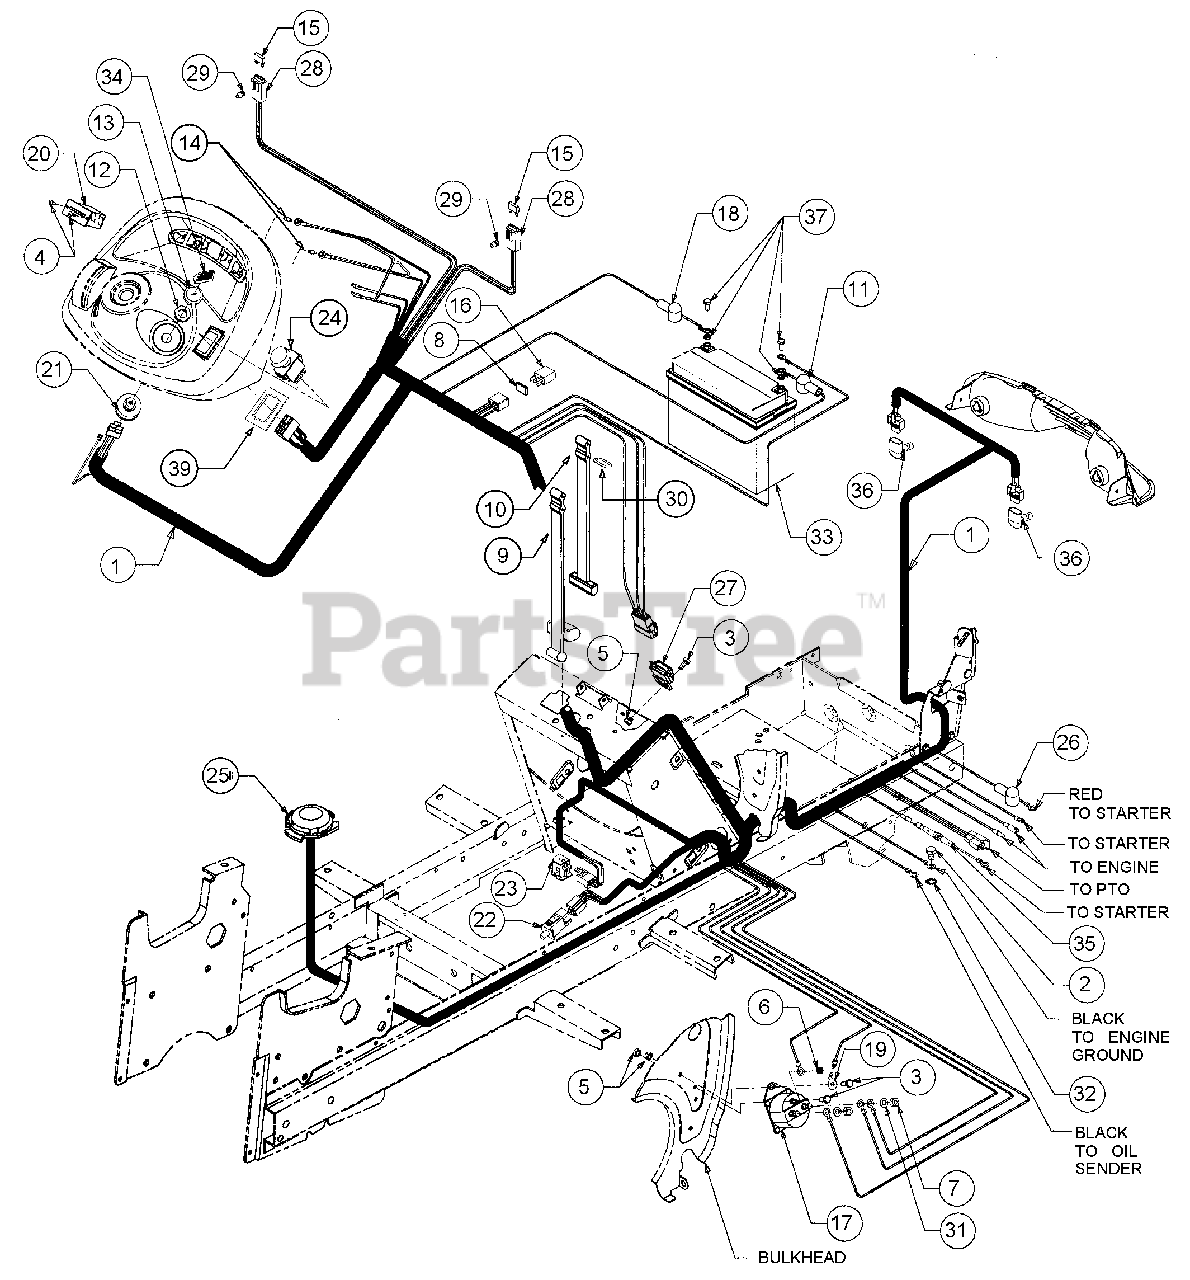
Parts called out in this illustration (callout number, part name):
1	Wire Harness, Main
2	Screw, Hex Cap, 3/8-16 x .50
3	Screw, Hex Cap, 1/4-20 x .625
4	Screw, Truss Hd Tapp, #6 x .62
5	Nut, Hex Sems, 1/4-20
6	Nut, Hex, #10-32
7	Nut, Hex, 5/16-18 GR5
8	Gasket, Silicone
9	Strap, Battery Retainer
11	Cover, Terminal Black
12	Nut, Ignition Switch
13	Cap, Ignition Switch
14	Bulb, Indicator
15	Fuse, 20 Amp
16	Relay
17	Solenoid, Starter
18	Cover, Terminal Red
19	Lug, Quick Connect
20	Hour Meter
21	Switch, Ignition
22	Switch, Interlock (Brake)
23	Switch, Snap Mount - Normally Closed
24	Switch, PTO
25	Switch, Seat
26	Cover, Terminal Red
27	Module, Voltage Sensor
28	Holder, Fuse w/Mounting Clip
30	Hook, Wire Rectangular
31	Washer, Lock, 5/16
32	Washer, External Lock, 3/8
33	Battery
34	Key, Ignition
35	Diode Assembly w/Lead
36	Bulb, Head Lamp
37	Battery Cable Hardware
39	Bracket, PTO Switch Retainer
